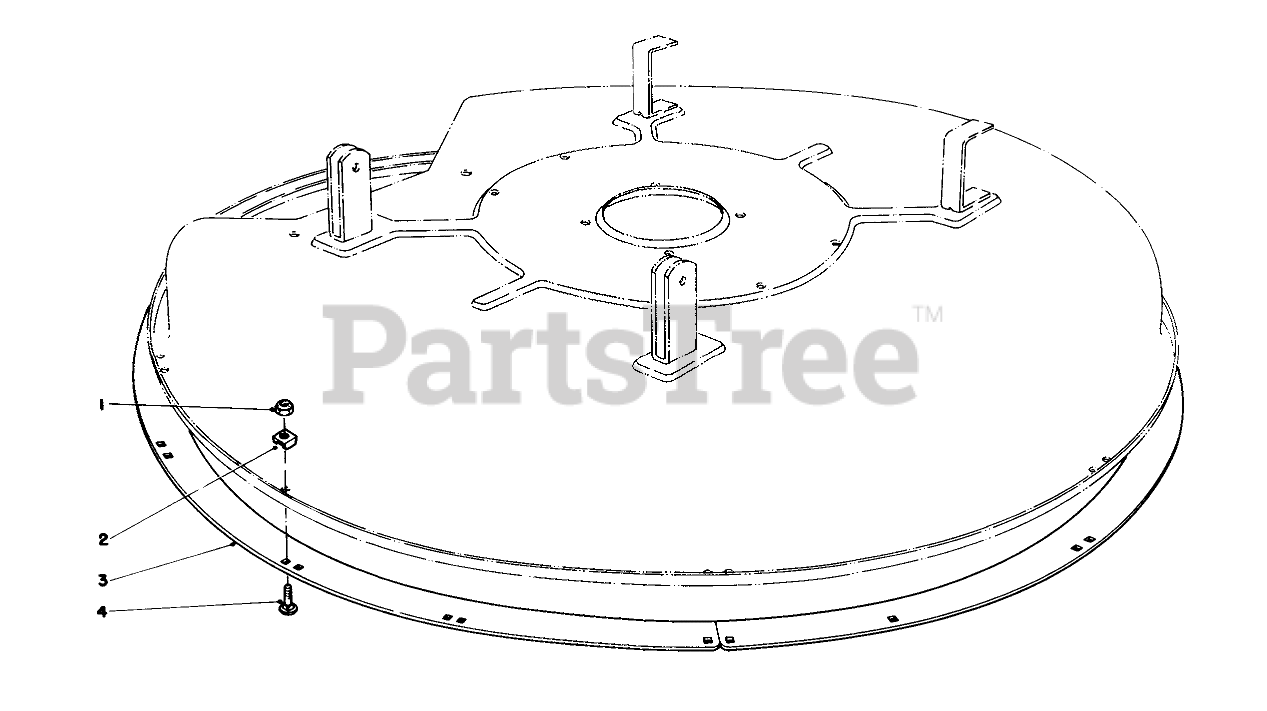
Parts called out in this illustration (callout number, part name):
1	NUT-LOCK, NI
2	DECK RING SPACER
3	DECK RING B
4	BOLT-CARR
